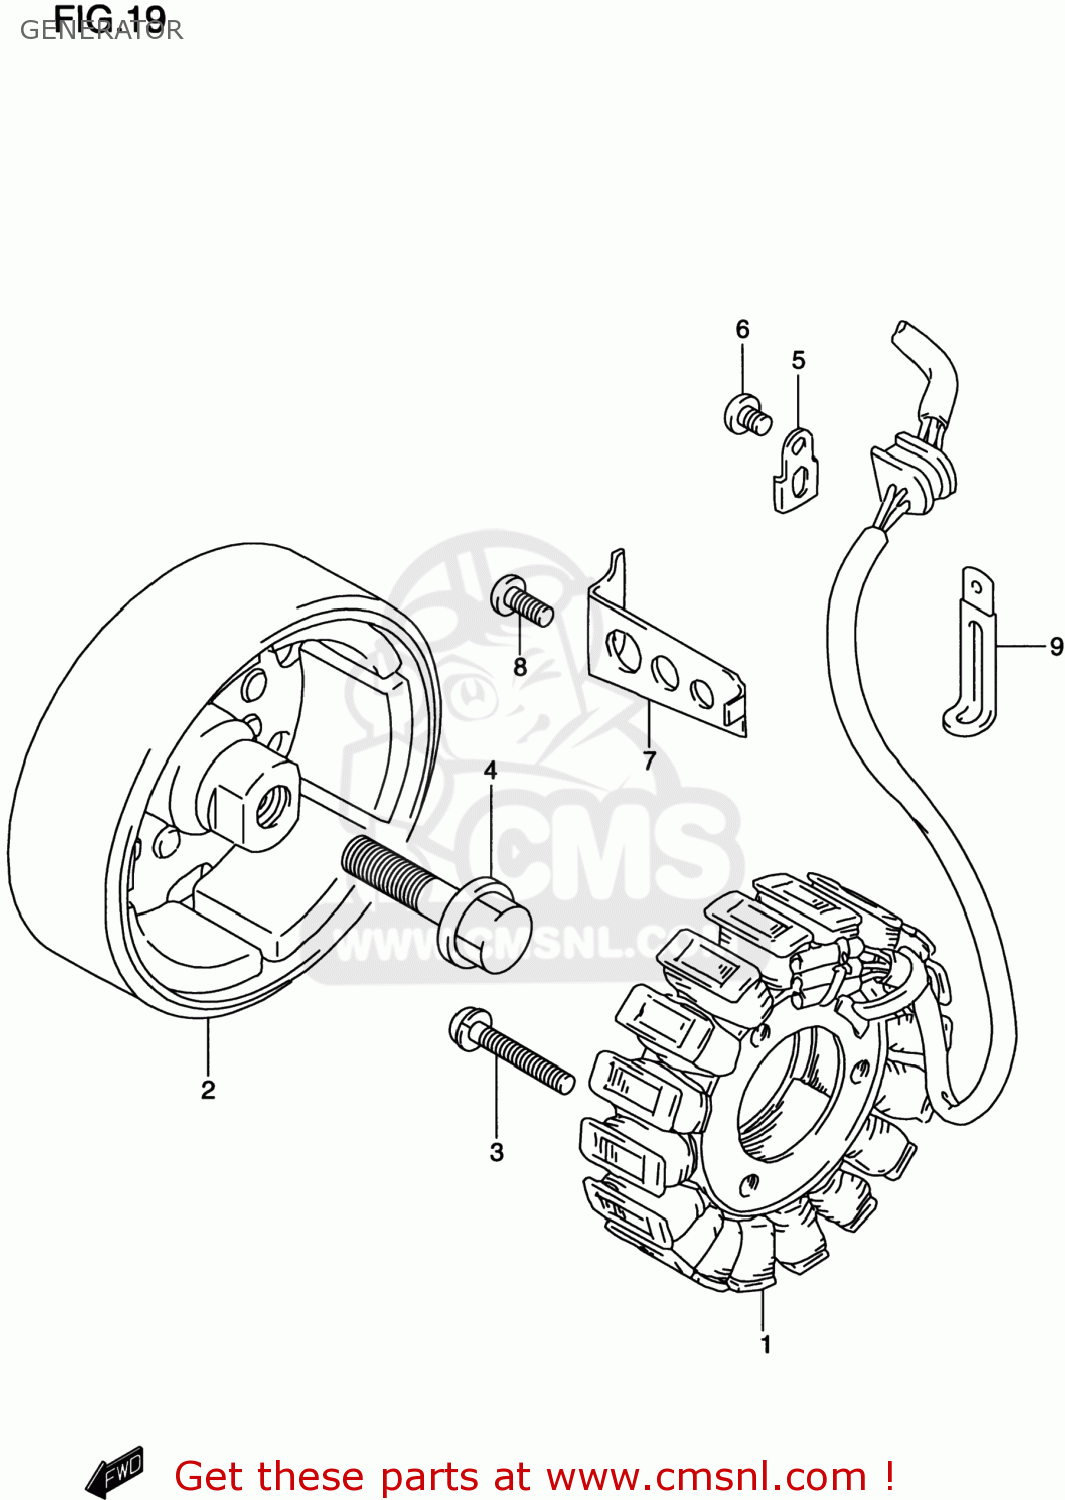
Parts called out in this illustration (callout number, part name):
1	STARTER ASSY
2	ROTOR ASSY
3	SCREW
4	BOLT(12X40)
5	CLAMP,GENERATOR LEAD WIRE
6	SCREW
7	CLAMP,GENERATOR LEAD WIRE
8	SCREW
9	CLAMP(L:45)
